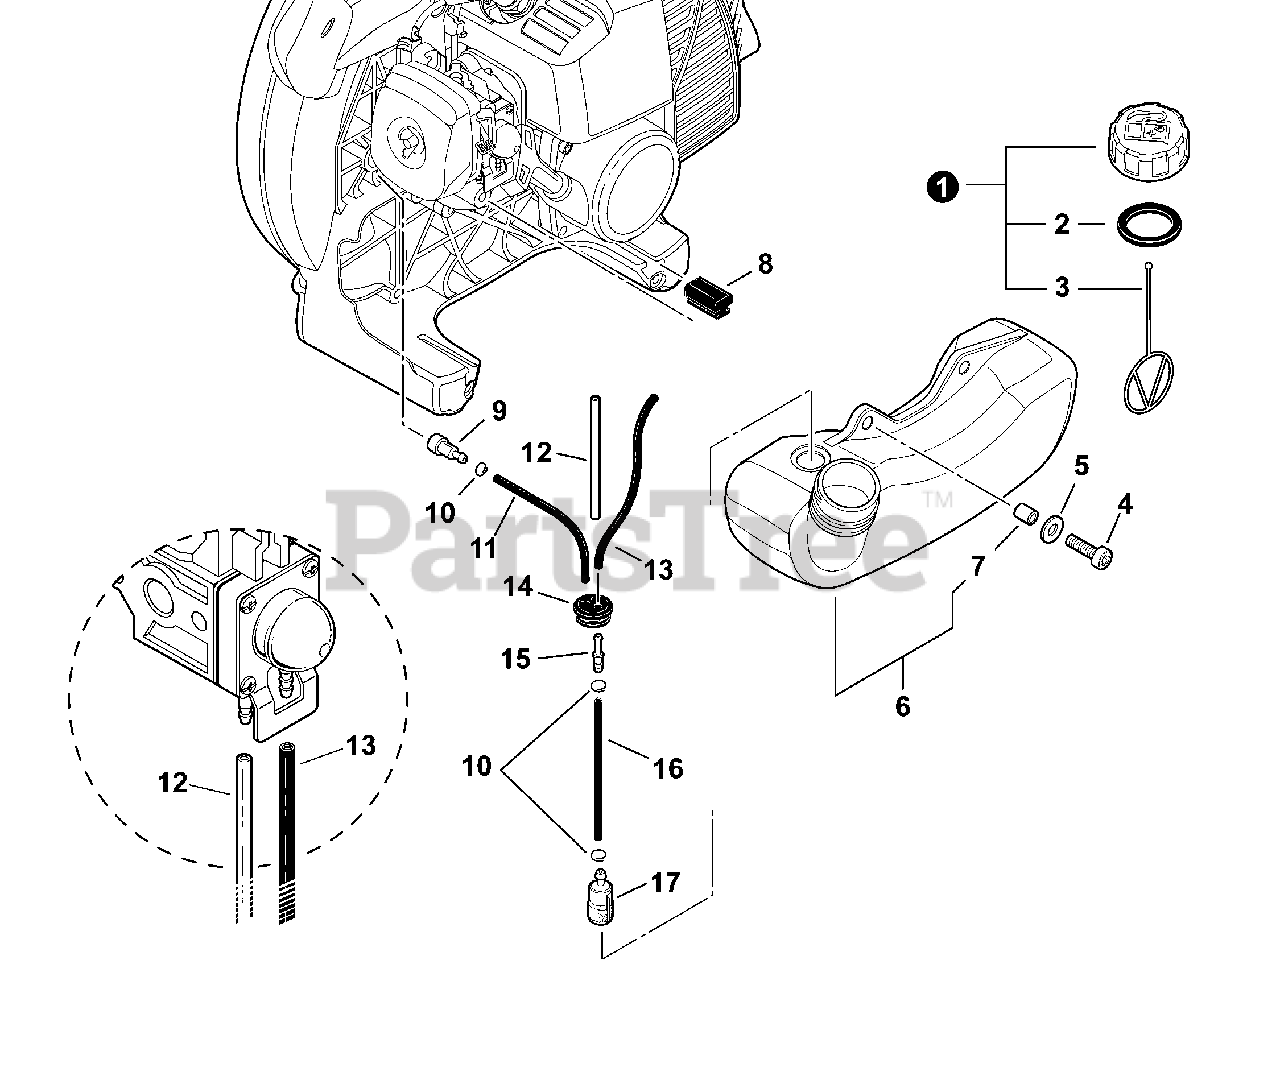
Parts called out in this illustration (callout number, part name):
1	CAP ASSY, FUEL
2	CONNECTOR, CAP L= 100 MM
3	GASKET, FUEL CAP
4	BOLT, TORX 5×16
5	WASHER 5.5×12×0.8
6	TANK ASSY, FUEL
7	SPACER 6.2×7.8×6
9	VENT ASSY
10	CLIP Ø6
11	PIPE, FUEL 3×5×80 BLACK
12	PIPE, FUEL 3×6×85 CLEAR
13	PIPE, FUEL 3×5×78 BLACK
14	GROMMET, FUEL Ø5
15	CONNECTOR, PIPE Ø5ר3.5
16	PIPE, FUEL 3×5×130 BLACK
17	FILTER, FUEL
